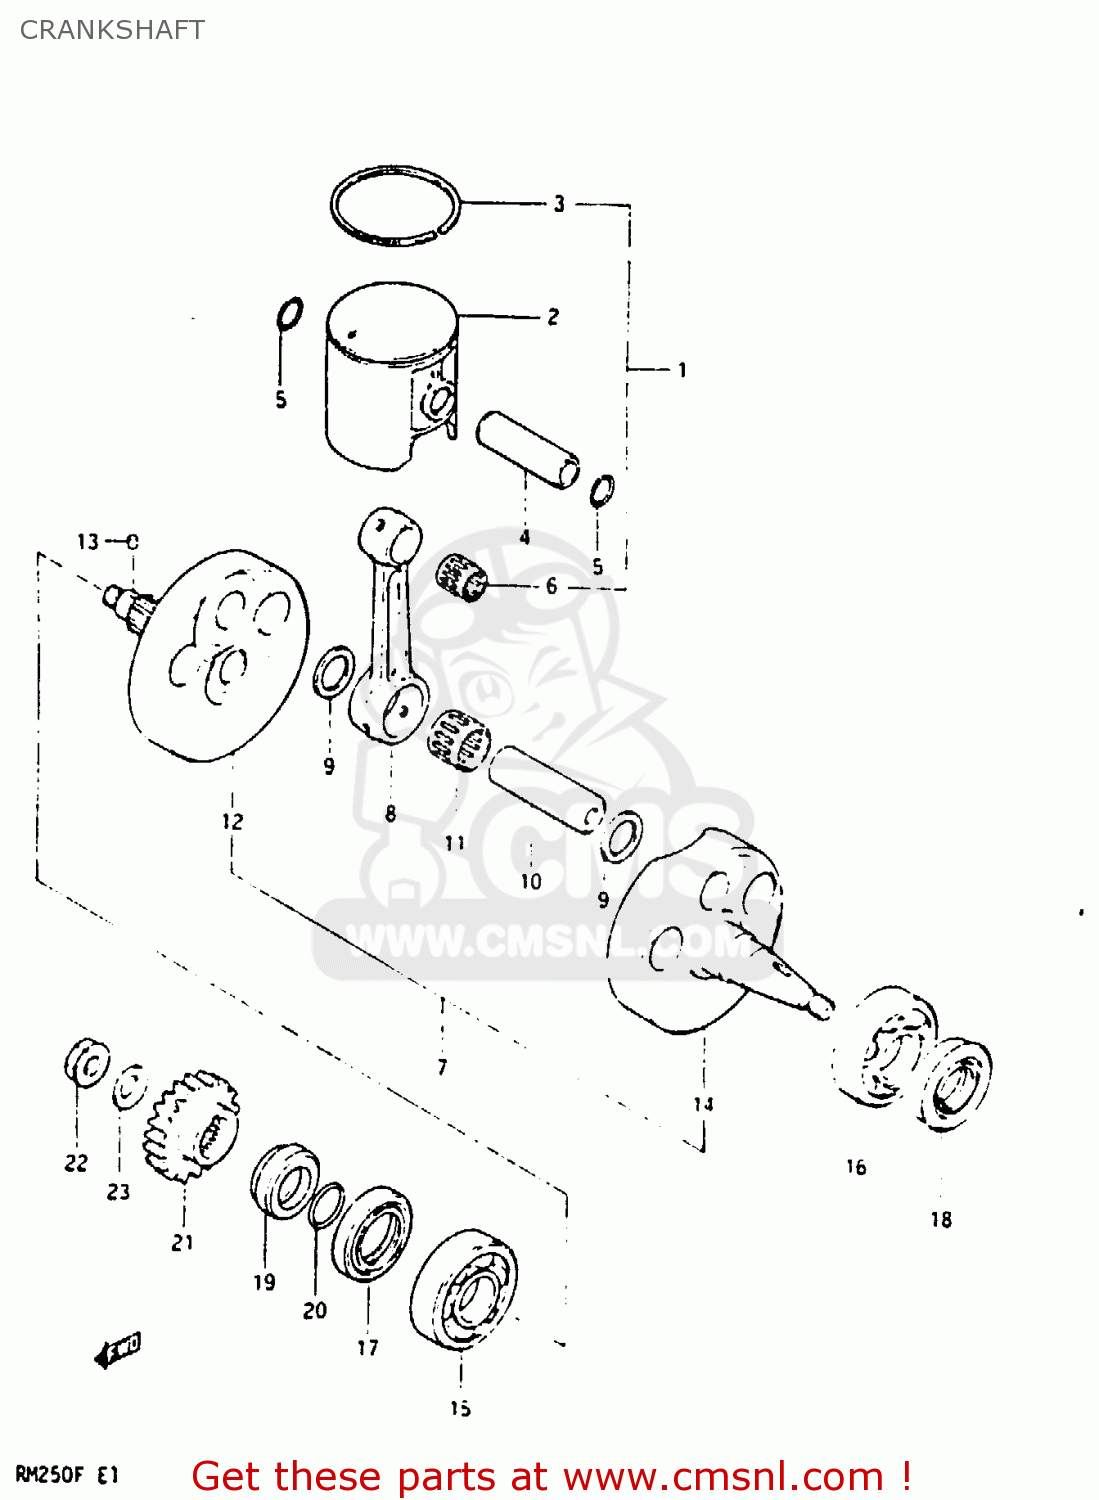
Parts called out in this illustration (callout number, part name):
1	PISTON SET (STD)
2	PISTON (70.00MM)
3	RING,PISTON
4	PIN,PISTON (18MM)
5	CIRCLIP,PISTON PIN
6	BEARING(18X23X22)
7	CRANKSHAFT ASSY
8	ROD,CONNECTING
9	WASHER(24X29X1.5)
10	PIN,CRANK
11	BEARING
12	CRANKSHAFT
13	PIN 3X5
14	CRANKSHAFT,LEFT
15	BEARING(25X62X17)
16	BEARING(30X62X16)
17	SEAL,OIL(36X52X8)
18	SEAL,OIL(19.6X37X8)
19	SPACER,PRIMARY DRIVE GEAR
20	O RING(D:2.4,ID:21.8)
21	GEAR,PRIMARY DRIVE
22	NUT
23	WASHER
